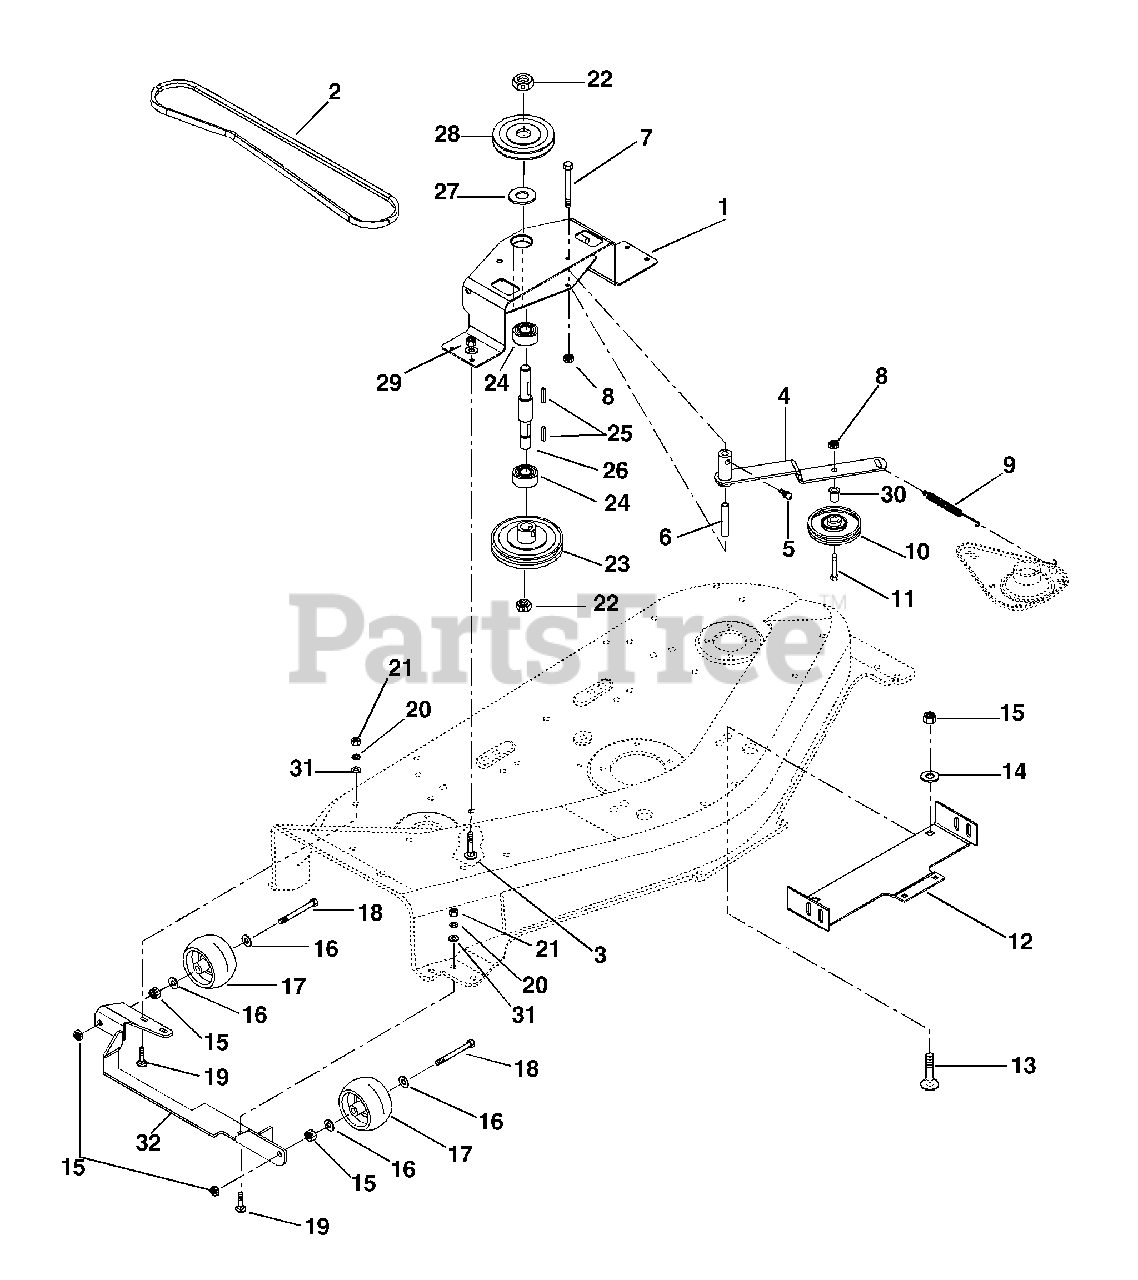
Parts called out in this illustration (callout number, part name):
1	HOUSING-JACKSHAFT
2	V-BELT, 5L-RAW EDGE
3	BLT-RDHDSQSHK.31-18X.75 GR2 YW
4	ARM, IDLER
5	FTG-LUBE .25-28X.256 YWZC
6	SPACER .334X.500X2.73
7	@BLT-HEX .31-18X3.50 GR5 YWZC
8	@NUT-LK-CTR .38-16 YWZC
9	SG-TENS .113X.812X7.00
10	IDLER, PLASTIC, 4.00 X .50 ID
11	@BLT-HEX .38-16X1.50 GR5 YWZC
12	BRACE, FRONT
13	@BLT-RDHDSQNK .50-13X.75 G5YZ
14	WSHR-FL-STL .505X.880X.072 YWZ
15	@NUT-LK-CTR .50-13 YWZC
16	WSHR-FL-NYL .518X1.000X.080
17	WHEEL 5 X 3
18	@BLT-HEX .50-13X4.50 GR5 YWZC
19	@BLT-RDHDSQNK .31-18X.75 G5YZ
20	WSHR-LK .312X.097 HVY YWZC
21	@NUT-HEX .31-18 YWZC
22	@NUT-LK-CTR .75-10 YWZC
23	PLY-V 6.00 X .75 W/KEY
24	BRG-BALL .750X1.781X.61
25	KEY-SQ .187 X .50 X .187
26	JACKSHAFT
27	WSHR-FL-STL .755X1.25X.125 YZ
29	@NUT-LK-CTR .31-18 YWZC
30	SPACER -FLANGED .390X.500X.781
31	WSHR-FL-STL .38X.875X.083 PL
32	MOUNT ROLLER
33	@WSHR-FL-STL.281X.62X.065 YWZC
34	@NUT-LK-CTR .25-20 YWZC
